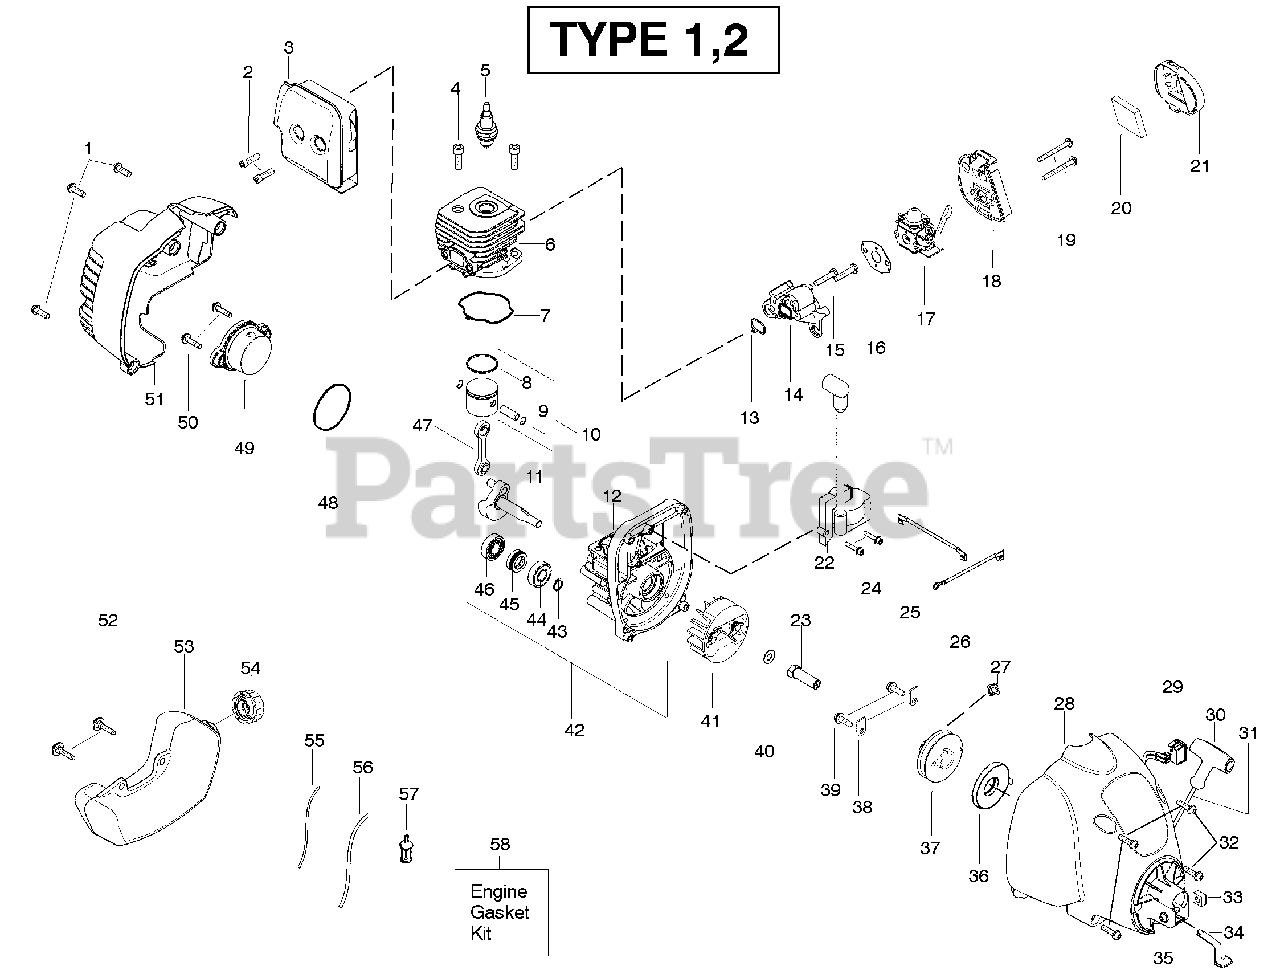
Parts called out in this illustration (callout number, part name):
2	Bolt-Muffler
3	Assy-Muffler/Shield
4	Screw-Cylinder
5	Spark Plug (RCJ 6Y)
6	Cylinder
7	Seal-Cylinder (kit)
8	Piston Ring
9	Retainer-Piston Pin
10	Kit - Piston
11	Assy-Crankshaft
12	Assy-Crankcase
13	Seal-Cyl/Carb.(kit)
14	Adapter-Carb.
16	Gasket-Carb. (kit)
17	Kit-Carb. Zama (C1U-W18)
17	Kit-Carb. Walbro ( WT-669)
18	Air Box
20	Foam-Air Filter
21	Cover-Air Box
22	Ignition Module
23	Coupling-Drive
25	Assy-Leadwire
26	Assy-Ground Wire
28	Assy.-Fan Hsg
29	Kit-Switch
30	Handle-Starter
31	Kit - Rope
32	Screw
34	Clip-Spring
36	Spring-Starter
37	Kit-Pulley-Starter
38	Retainer-Pulley
40	Washer-Flat
41	Assy-Flywheel
42	Assy-C'case & C'shaft
43	Retain. Ring-C'shaft
44	Outer Bearing
45	Seal-C'case
46	Inner Bearing
47	Assy-Connecting Rod
48	O-Ring-C'case (kit)
49	Assy-Plug
51	Shroud-Rear Green
51	Shroud-Rear Black
52	Retainer-Tank
53	Assy-Fuel Tank
54	Assy-Fuel Cap
55	Kit-Fuel Line (Small)
56	Kit-Fuel Line (Large)
57	Assy-Fuel Pickup
58	Kit-Engine Gasket
